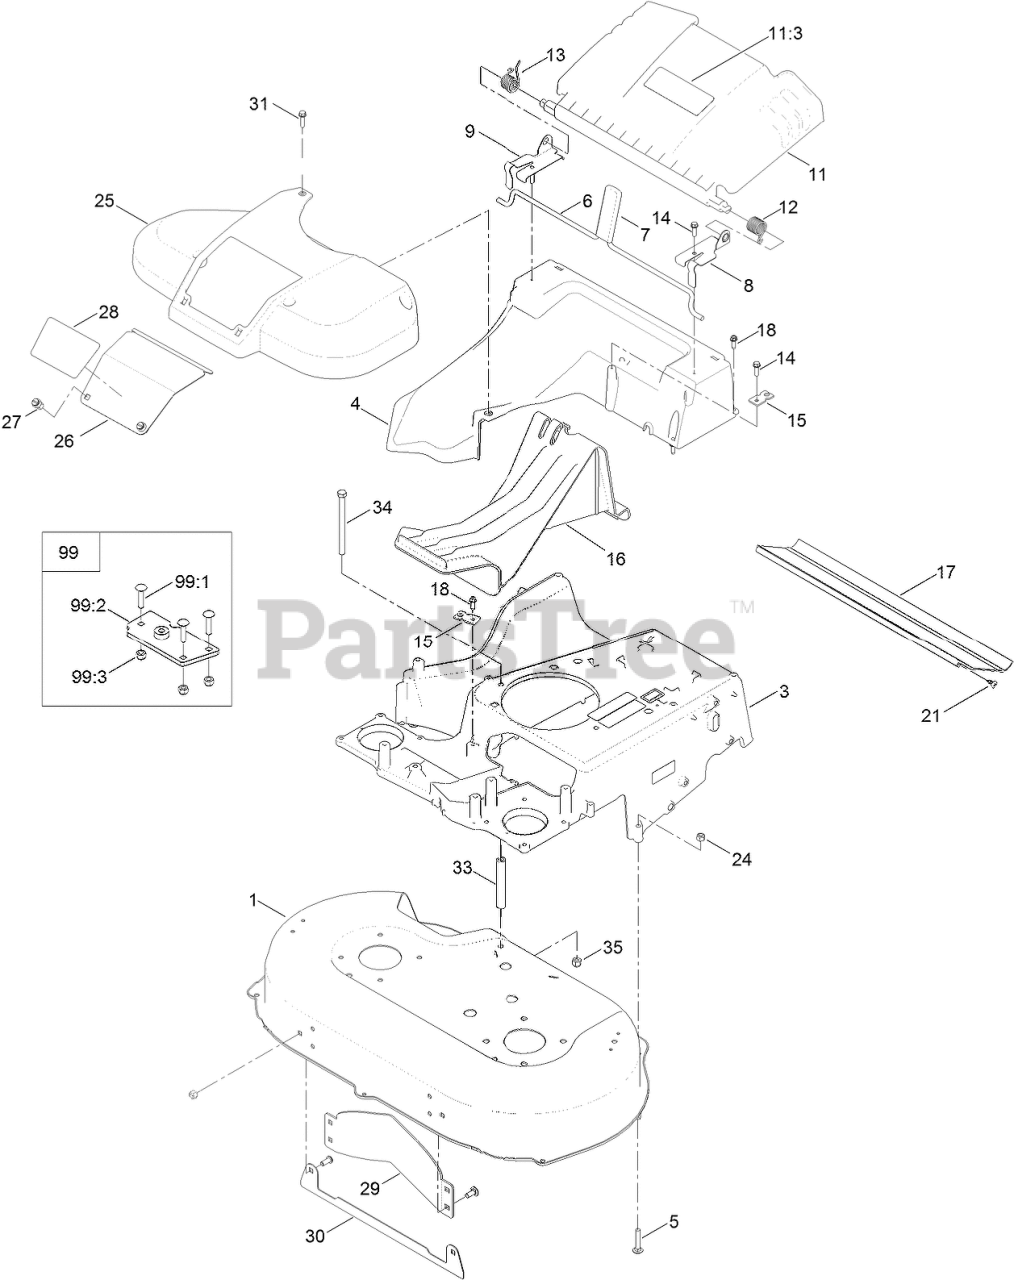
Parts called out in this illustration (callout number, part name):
1	HOUSING ASM
3	FRAME
5	SCREW-CARR
6	ROD-RELEASE, HANDLE
7	GRIP-LEVER
8	BRACKET-DOOR, LH
9	BRACKET-DOOR, RH
11	REAR DEFLECTOR ASM
11:3	DECAL-WARNING
12	SPRING-TORSION
13	SPRING-TORSION
14	SCREW-HWH
15	BRACKET-CABLE, TRACTION
16	PLUG-MULCH
17	SHIELD-TRAILING
18	SCREW-HWHTF
21	SCREW-PTH
24	NUT-LOCK, NI
25	COVER-BELT
26	DOOR-ACCESS
27	FASTENER
28	DECAL-ACCESS PANEL
29	BAFFLE-CONTROL
30	PLATE-DECK
31	SCREW-HWHTF
33	SPACER-SHIELD
34	SCREW-HH
35	NUT-LOCK, NI
99	FRAME PLATE KIT
99:1	PLATE-FRAME
99:2	SCREW-CARR
99:3	NUT-LOCK, NI
